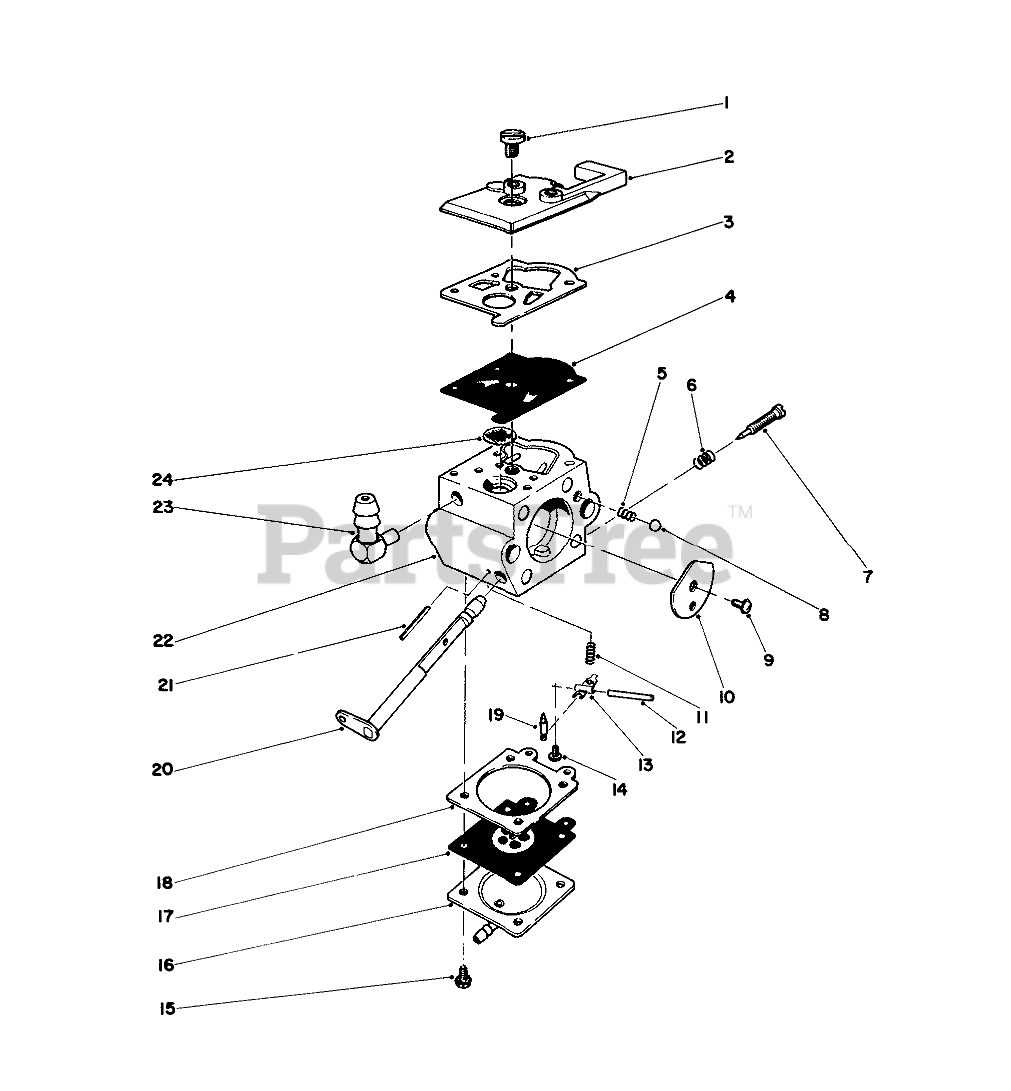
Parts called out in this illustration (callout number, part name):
1	PUMP COVER SCREW
2	Pump Cover
3	PUMP GASKET
4	PUMP DIAPHRAGM
5	CHOKE SPRING
6	Spring-Needle (Hi)
7	HIGH SPEED NEEDLE
8	CHOKE BALL
9	VALVE SCREW
10	Choke Valve
11	Metering Lever Spring
12	Metering Lever Pin
13	Lever Metering
14	Screw-Metering Pin
15	Screw
16	Metering Diaphragm Cover
17	METERING DIAPHRAGM
18	Gasket-Metering Diaphragm
19	NEEDLE VALVE
20	CHOKE SHAFT ASM
21	Roll Pin
23	FUEL FITTING
24	Inlet Screen
